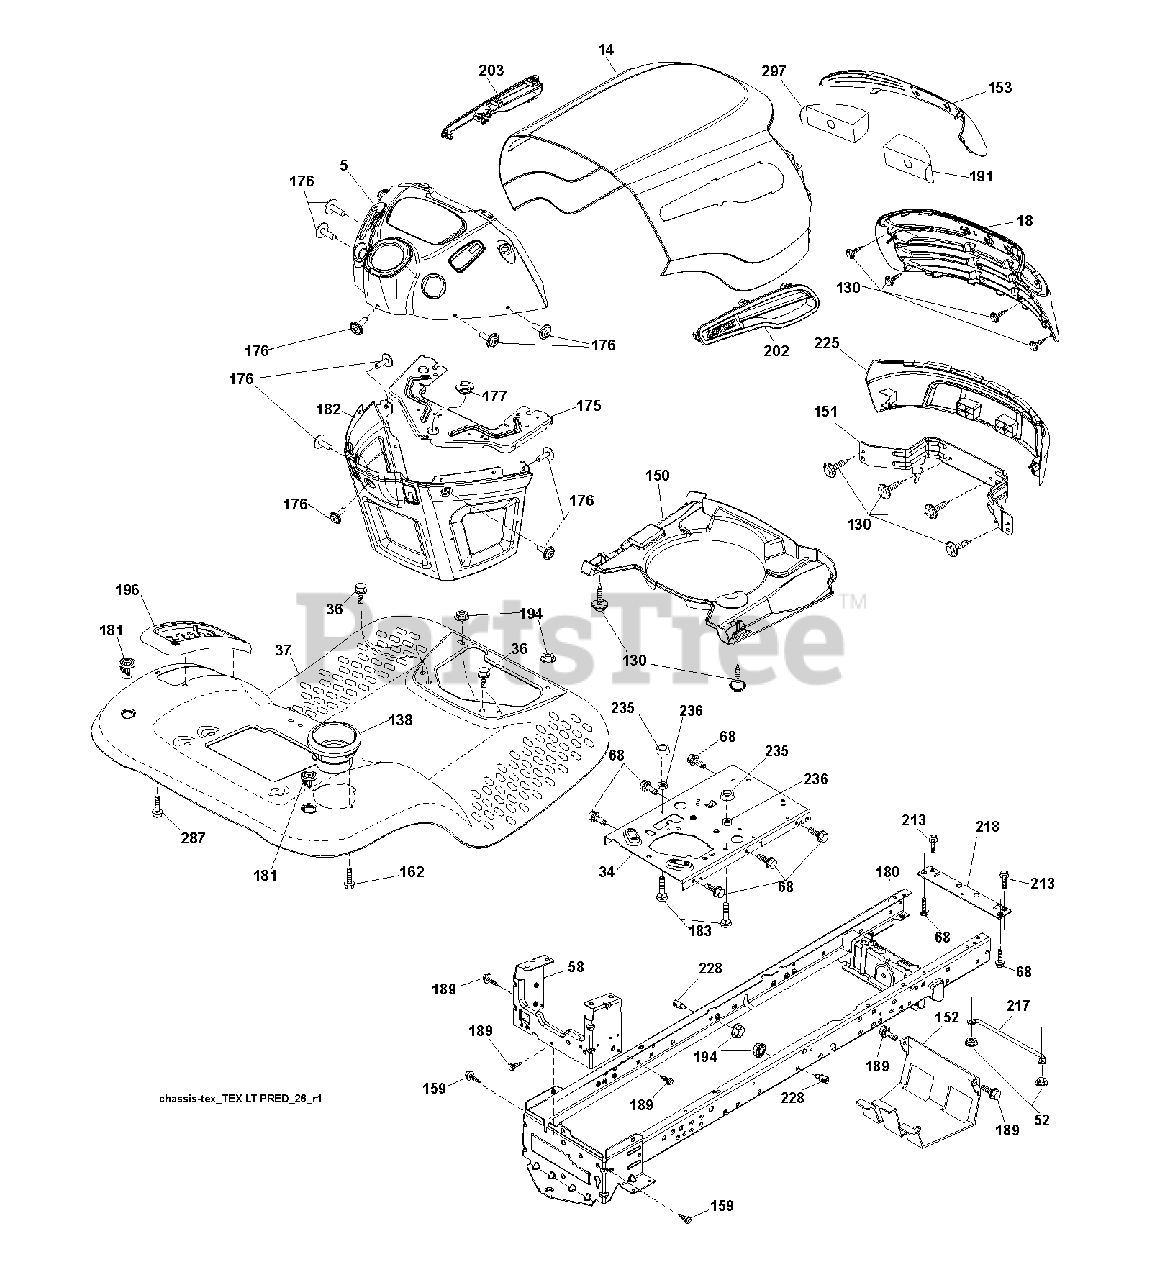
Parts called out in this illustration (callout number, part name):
5	DASH.PRED.LT.CC.ICY.SRVMDR.BLK
34	PLATE.ENGINE.WELDED.CHASSIS
36	SCREW 5/16"
52	LOCKNUT
58	DRAWBAR UPPER 2PC SMALL FENDER
130	SCREW.#10 X 0.750.BOS THREAD
138	CUPHOLDER.TL.TEX.BLACK
151	BRACKET.PIVOT.ALPHA.LT
152	SHIELD BROWNING
159	SCREW, 3/8-16X3/4
162	SCREW.HI-LO.CONSOLE
175	CROSSMEMBER
176	SCREW.#10-24X5/8.RN.QU
177	BUSHING STEERING
181	FEND/FTRST.PCH.CPH.NFW
182	DASH.LWER.PREDATOR/HUSQ.LT
183	BOLT.5/16-18X1-1/4 FULL.THREAD
189	SCREW
191	INSERT.REFLECT.PREDATOR.LT.RH
194	NUT LOCK HEX FLANGE 5/16-18
196	CONSOLE.ASM.DECKLFT.BL/RBT.TLT
213	BOLT
217	ROD.PIVOT.HOOD
218	X-PIECE.HOOD.STOP.NON/
228	STUD.FASTNER.W/ANTI-ROTATE
235	SPACER FENDER
236	NUT.CENTERLOCK.5/16-
297	REFLECTOR.INSERT.PRED.LH.LT
